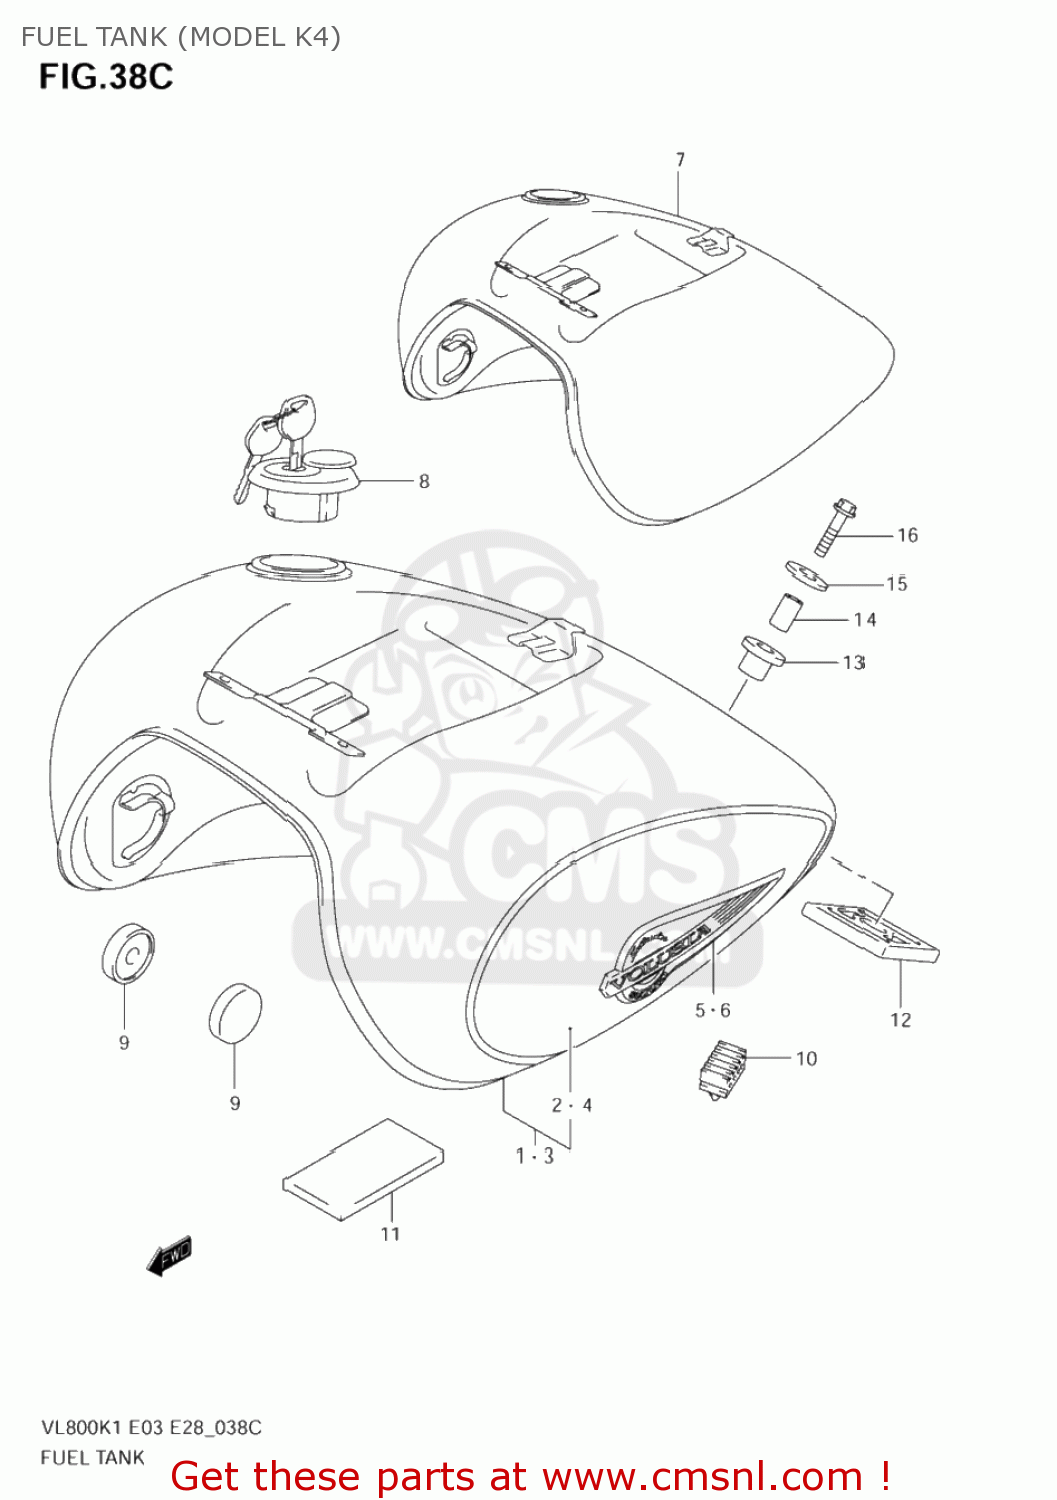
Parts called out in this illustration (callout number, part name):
1	TANK ASSY,FUEL(BLACK)
2	TAPE SET,FUEL TANK
3	TANK ASSY,FUEL
4	TAPE SET,FUEL TANK
5	EMBLEM,FUEL TANK,R
6	EMBLEM,FUEL TANK,L
7	TANK ASSY,FUEL(GRAY)
8	CAP SET,FUEL TANK
9	CUSHION
10	CUSHION,SEAT(40X20X15)
11	CUSHION,FUEL TANK
12	CUSHION,FUEL TANK RR LWR
13	CUSHION,FUEL T
14	SPACER (8.2X12.5X23.5)
15	WASHER (8.5X33X1.6)
16	BOLT
